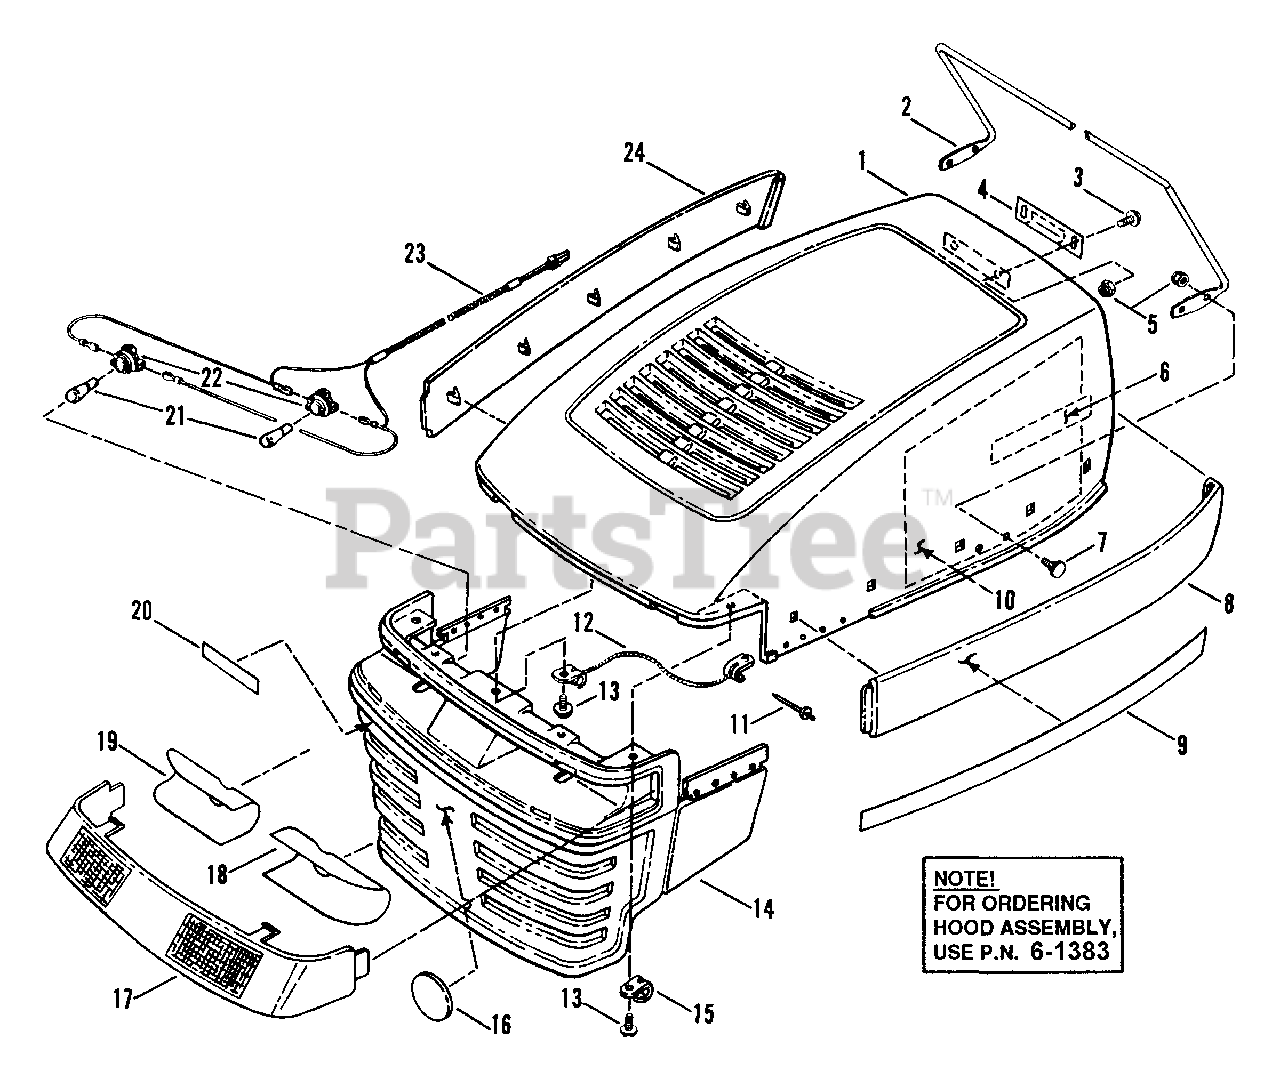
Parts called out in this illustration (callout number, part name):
1	HOOD
2	ROD, Hood Support
3	SCREW, 1/4-20 x 5/8" Truss Head
4	LATCH, Spring
5	NUT, 1/4-20 Hex Nyloc
6	LOGO - SNAPPER (Chrome)
7	BOLT, 1/4-20 x 5/8" Flat Head Carriage
8	PANEL, Hood (Left Side)
9	DECAL, Hood
10	HEAT SHIELD, Hood
11	RIVET, 1/8" Pop
12	LANYARD, Hood
13	SCREW, M4.8 x 1.59 x 16.00MM, Special
14	GRILLE, Hood
15	CLIP, 'J'
16	DECAL, Convertible
16	DECAL, Recycling, Ninja Blade
17	LENS
18	DECAL, Reflect (L.H.)
19	DECAL, Reflect (R.H.)
20	LOGO - SNAPPER, 4" (Chrome)
21	BULB, Headlights
22	SOCKET, Headlight Bulb
23	HARNESS, Headlight Wiring
24	PANEL, Hood (R.H.)
61383	Hood Assembly
